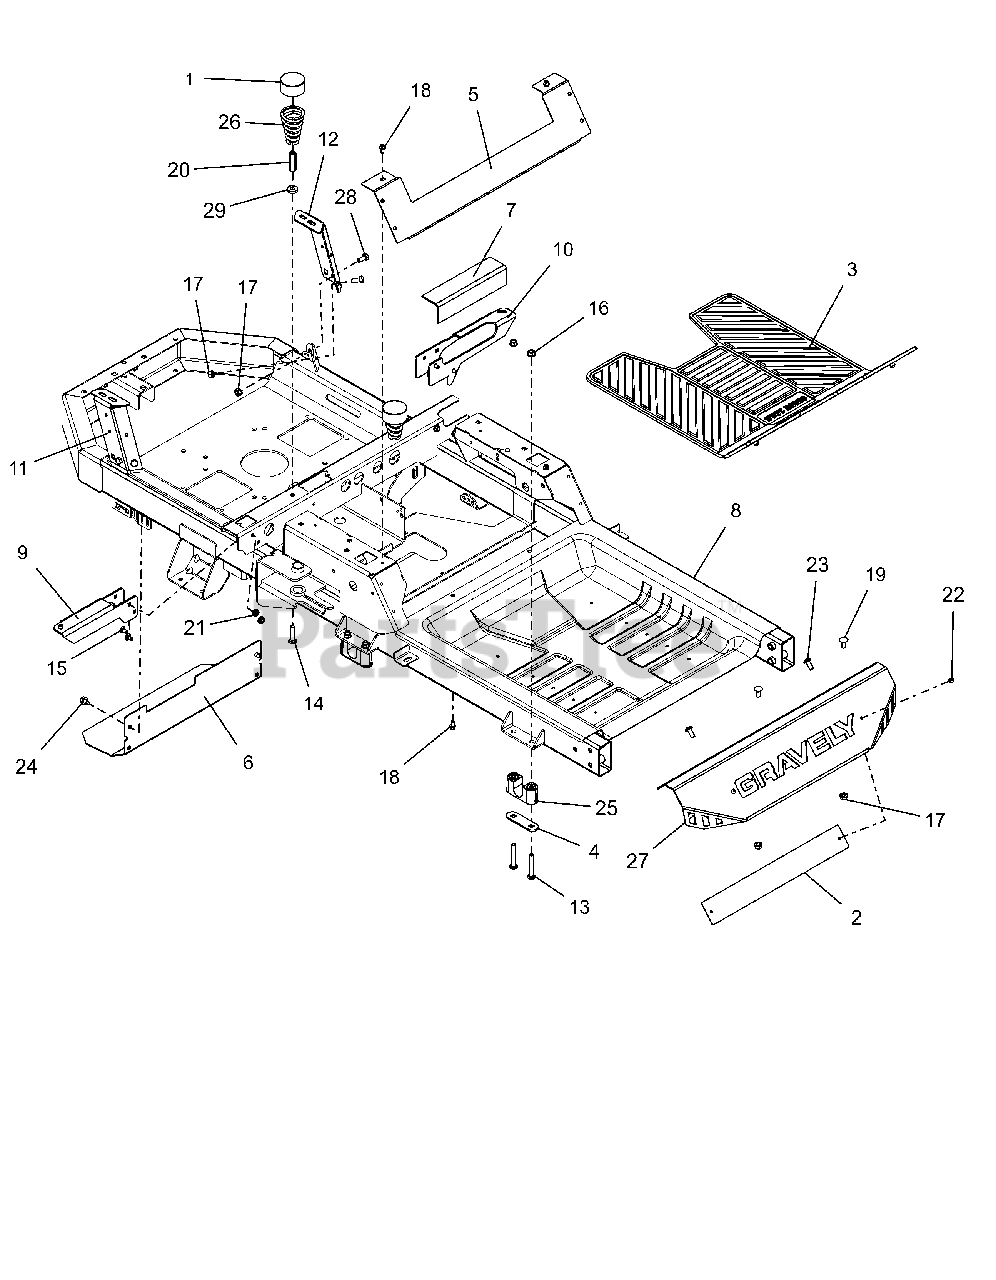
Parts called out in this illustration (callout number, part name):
2	PLATE, BACK FOOT-REST XL
3	FLOOR MAT, RUBBER - GRAVELY
4	PLATE, BEARING SUPPORT
5	PLATE, SEAT KICK
6	HEAT, SHIELD
7	PAD, RUBBER-TANK
8	KIT, ZT-X/XL FRAME SERVICE
9	BRKT,CROSS EXTENSION - LH
10	BRKT,CROSS EXTENSTION - RH
11	MOUNT,FENDER-RH EXTENSION
12	MOUNT,FENDER-LH EXTENSION
13	BLT-RDHDSQSHNK .31-18X2.25 YWZ
14	BLT,RHSN .31-18X1.50 G5 ZCC
15	BLT, RHSSN.25-20X.500 G5 ZCC
16	NUT,LK-CTR-FLG .31-18 GF ZCC
17	NUT-LK-TOP-FLG .312-18 GF ZCC
18	SCR-TAP .25-20X.50 HWH ZCC
19	BLT,RHSN .31-18X.75 G5 ZCC
20	NUT, COUPLING 5/16-18 X 1 3/4
21	NUT-LK-CTR-FLG .25-20 ZC120
22	RIVET, .1875 AL/AL .126-.250
23	SCR-RDHDSKTAP .31-18 X .75
24	SCR,TAP .312-18X.50 HWH TR ZCC
25	BSHG, DECK LIFT PIVOT
26	SPRING, SEAT
27	PLATE, FOOT - GRAVELY
28	BLT,HEX .31-18X.75 G5 ZCC
29	WSHR, FLT .328X.870X.179 ZCC
